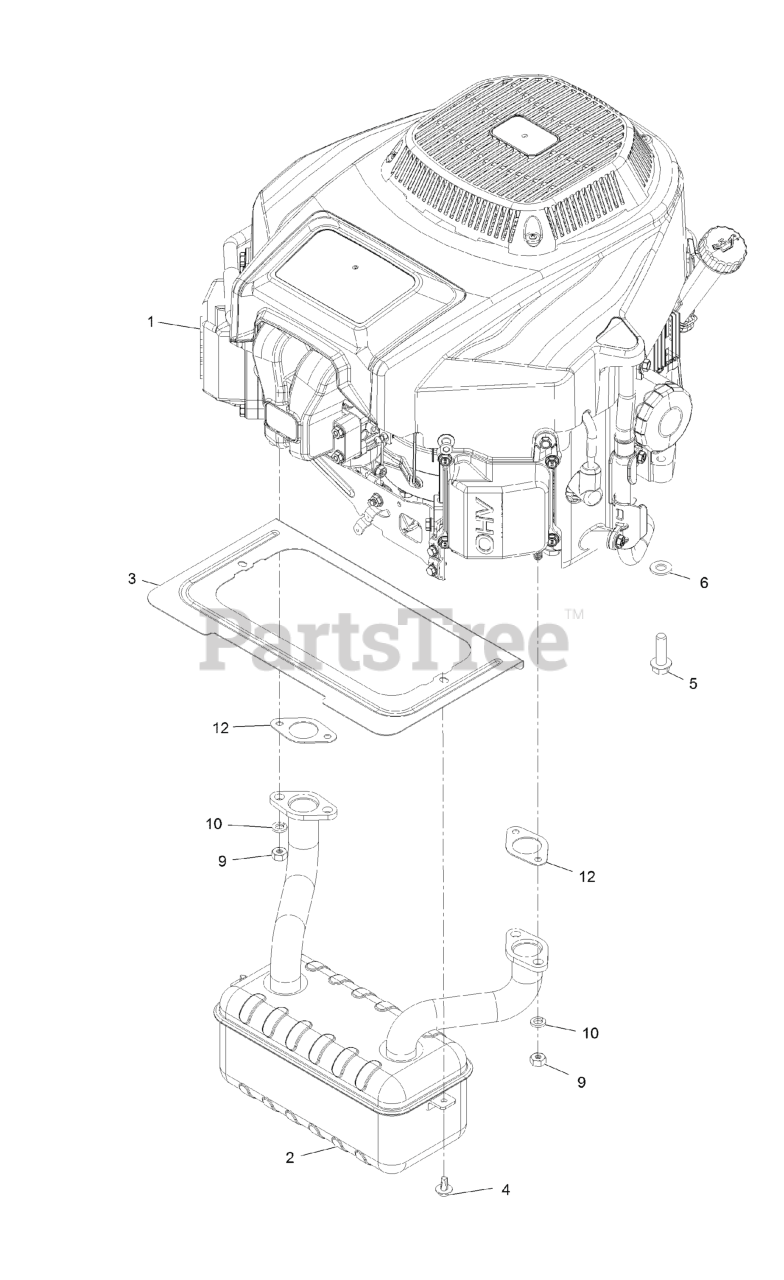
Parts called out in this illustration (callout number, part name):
1	Engine-2P77F
2	MUFFLER
3	SHIELD-HEAT
4	SCREW-HHFTF
5	SCREW-THD
6	WASHER-FLAT
10	WASHER-LOCK, SPLIT
12	GASKET-EXHAUST
